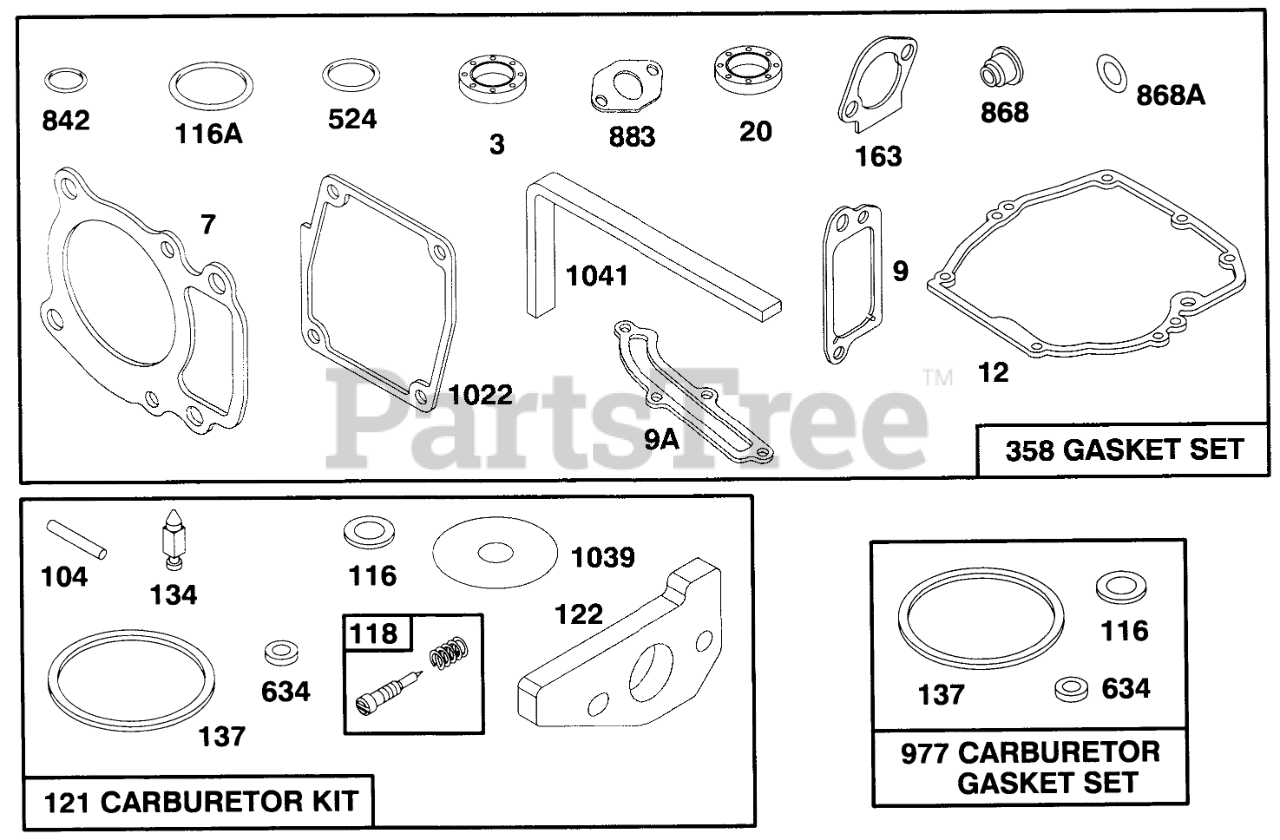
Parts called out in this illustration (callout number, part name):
3	SEAL - OIL
7	CYLINDER HEAD GASKET
9	BREATHER GASKET
9A	GASKET-BREATHER
12	ENGINE BASE GASKET
20	SEAL-OIL
104	FLOAT HINGE PIN
116	O RING SEAL
116A	SEALING GASKET
118	VALVE KIT - NEEDLE
121	CARBURATOR OVERHAUL KIT
122	ADAPTER ASSEMBLY
134	Valve-Inlet (Includes Seat)
137	FLOAT BOWL GASKET
163	AIR CLEANER GASKET
358	GASKET SET
524	O-RING
634	SEAL WASHER
842	O-RING
868	SealAssy-Valve
868A	Seal-Valve
883	EXHAUST GASKET
977	CARBURATOR GASKET SET
1022	ROCKER COVER GASKET
1039	FLOAT LIMITER
1041	SEAL - FOAM
